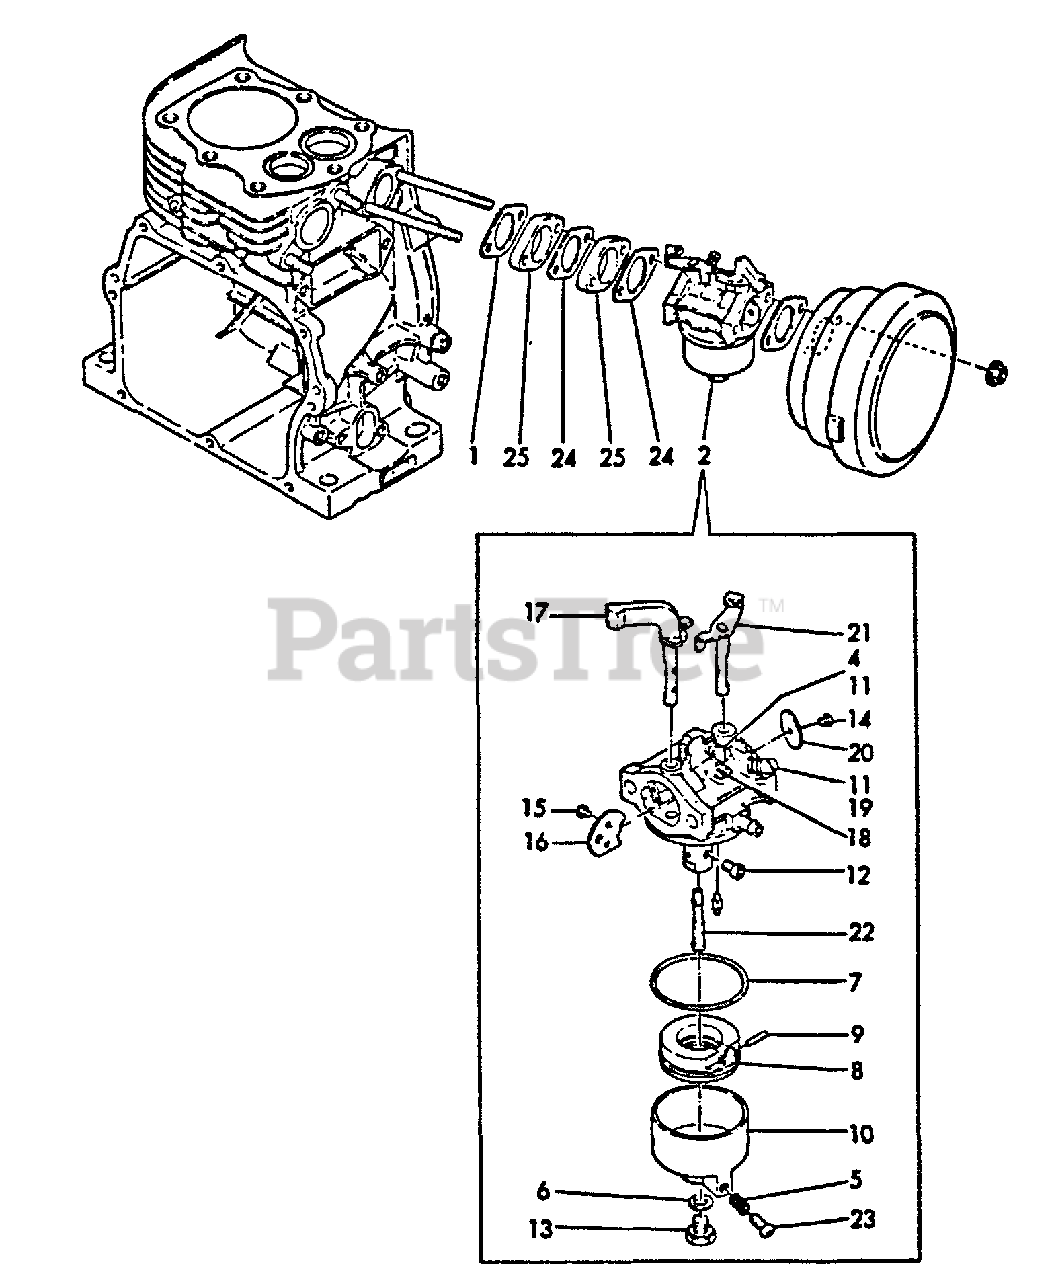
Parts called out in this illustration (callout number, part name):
1	GASKET, EXHAUST
2	CARBURETOR
4	SCREW, THROTTLE
6	WASHER
7	GASKET
8	FLOAT
9	PIN
10	BODY, FLOAT CHAMBER
11	SPRING
12	JET, MAIN
13	BOLT
14	SCREW
15	SCREW -- TAPPING
16	VALVE, CHOKE
17	SHAFT, CHOKE
18	JET, PILOT
19	SCREW
20	VALVE, THROTTLE
21	SHAFT, THROTTLE
22	NOZZLE, MAIN
23	SCREW
24	GASKET, INTAKE
25	INSULATOR, INTAKE
